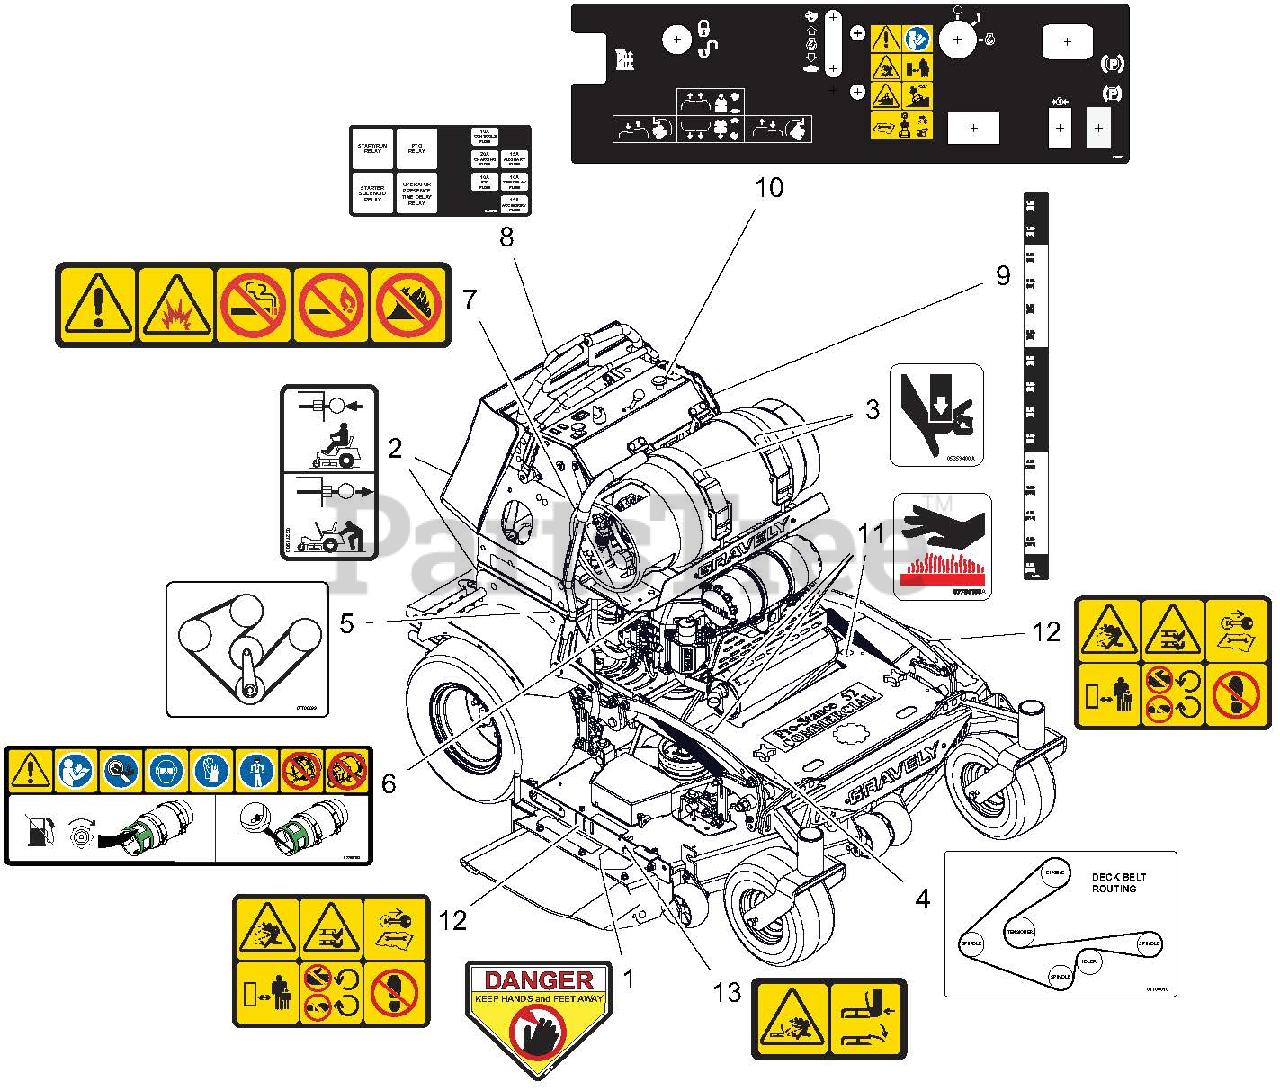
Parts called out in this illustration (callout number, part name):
1	DECAL, DANGER
2	DECAL, TRANSMISSION DISCONNECT
3	DECAL, PINCH POINT
4	DECAL, BELT ROUTING 48/52 REV
5	DECAL, HYDRO BELT
6	DECAL, HORZ. MOWER TANKS ONLY
7	DECAL, SAFETY -LP
8	DECAL, FUSE BLOCK
9	DECAL, HEIGHT OF CUT - PROSTANCE
10	DECAL, CONTROL PANEL EFI
11	DECAL HOT SURFACE
12	DECAL, SAFETY - MOWER DECK
13	DECAL, SAFETY - DECK GUARDING
